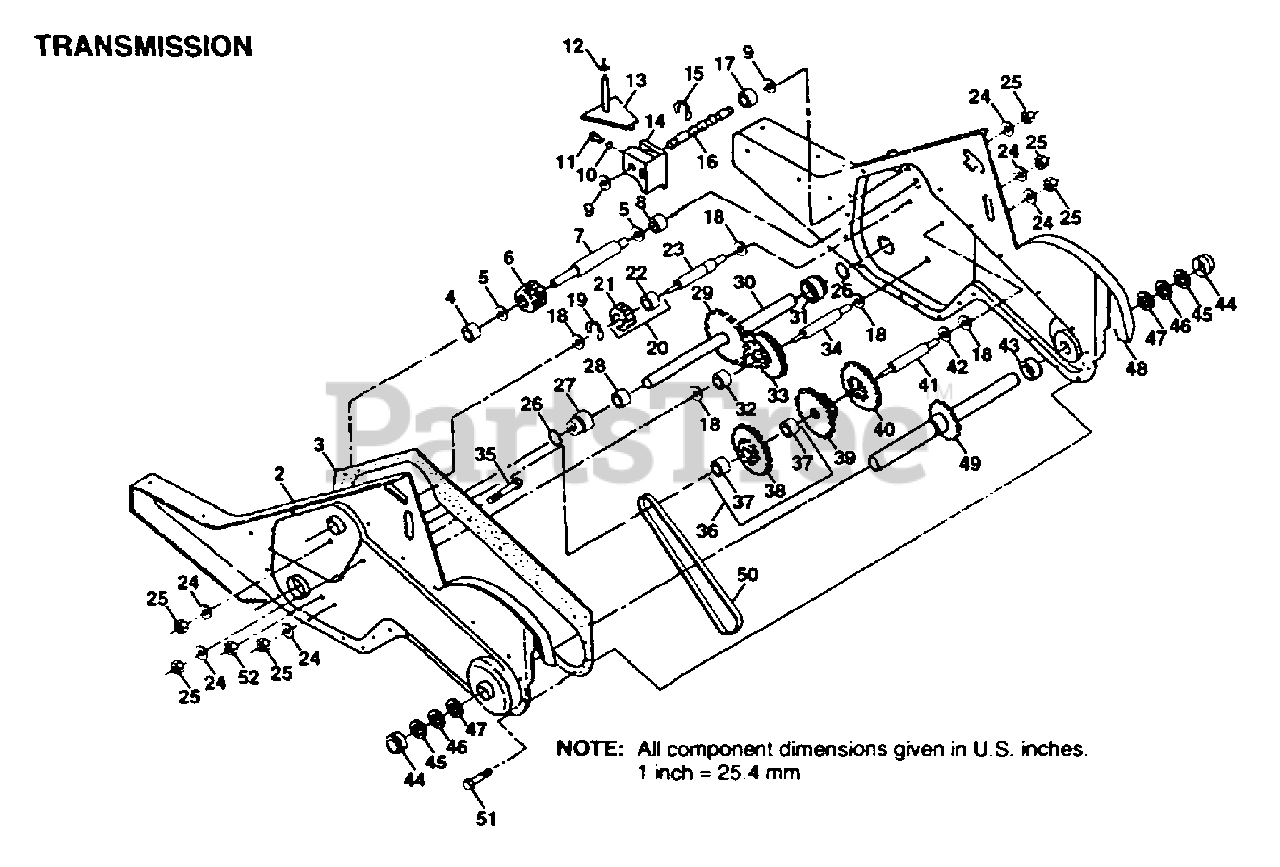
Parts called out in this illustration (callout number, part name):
3	GASKET TI
4	NEEDLE BRNG LT
5	"T, BEARING"
6	PINION-INPUT CRT
7	SHAFT-INPUT CRT
8	"TI, BEARING"
9	WASHER SEAL CRT
10	BALL, STEEL
11	SPRING-SHIFT CRT
12	O-RING TI
13	ARM ASSY CRT
14	SHIFT FORK TI
15	KLIP RING
16	SHAFT SHIFT CRT
17	SPACER SPLIT CRT
18	WASHER
19	KLIP RING
20	GEAR ASSY CRT
21	GEAR-REV IDLR CRT
22	NEEDLE BEARING TI
23	SHAFT CRT
25	LOCKWASHER
26	O RING CRT
27	"CRT, BEARING"
28	BUSHING TI
32	SPACER TI
33	SPRCKT 8 GEAR CRT
34	SHFT 2ND RED. CRT
35	SCRW WHIZ LOK CRT
36	SPROCKET ASM.
37	BEARING
39	GEAR TI
40	GEAR TI
41	REDUCTION SHFT TI
43	BRNG RACE
44	CUP.FORMED.
45	RING SPIRAL CRT
49	TINE SHAFT
50	CHAIN.50 LINK TI
51	SCREW CRT
52	NUT.HEX.5/16-18
